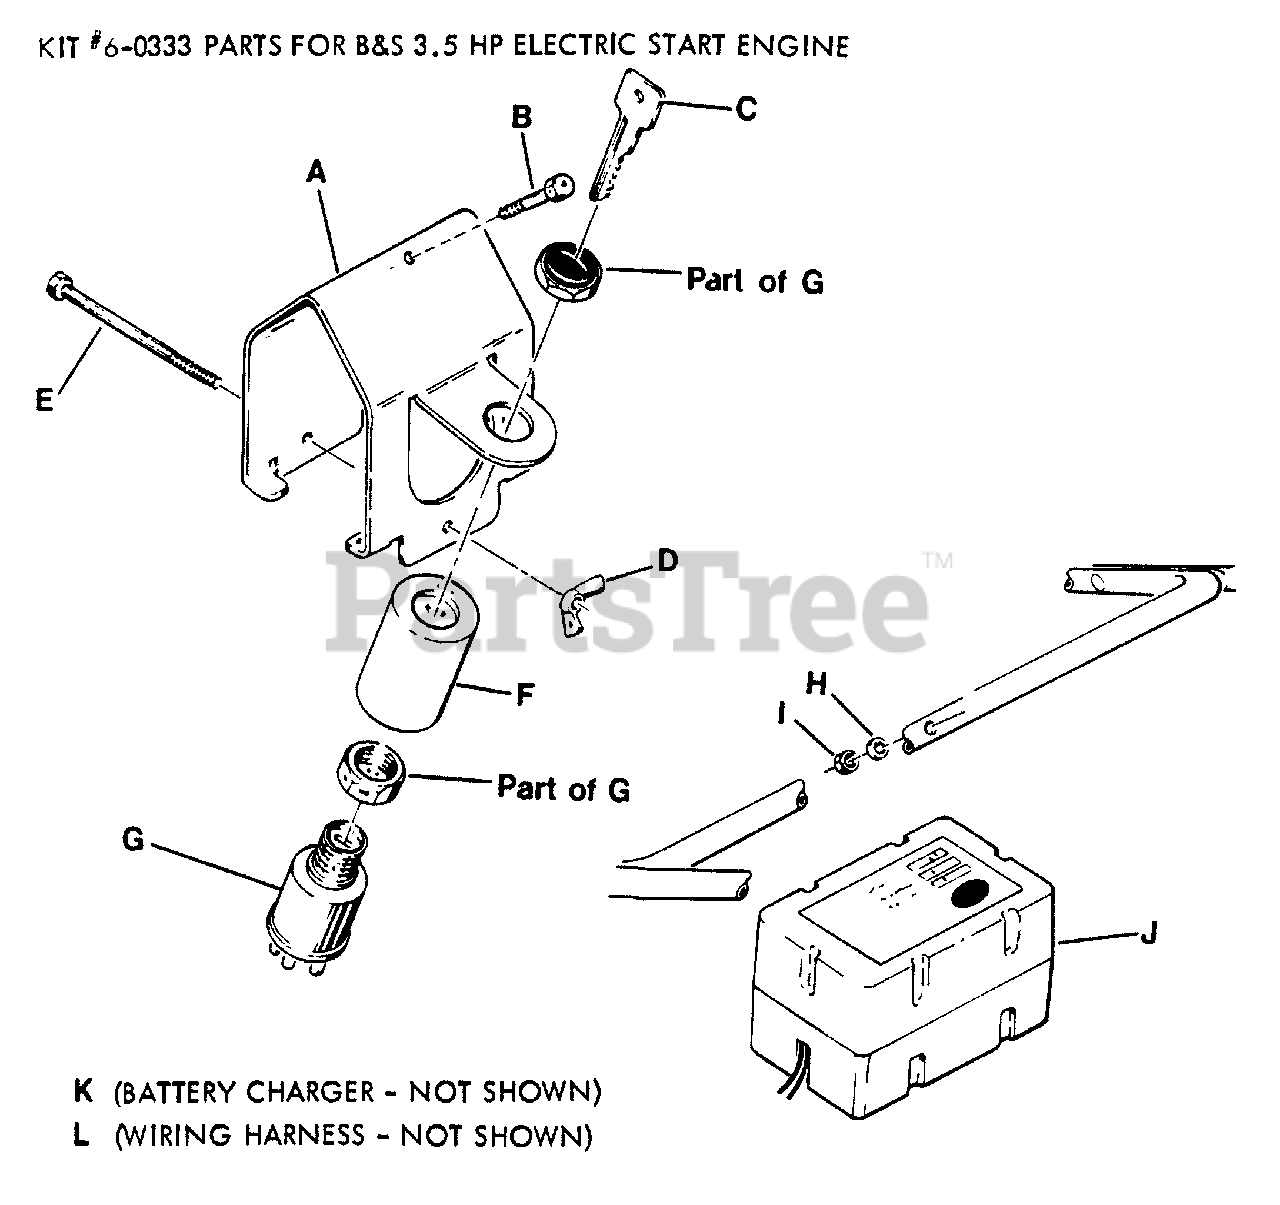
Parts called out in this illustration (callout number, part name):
60333	ELECTRIC START ENGINE
A	ASSEMBLY, Bracket
B	SCREW, 1/4-28 x 1-1/4" Hex Head Cap, Grade 5
C	KEY
D	NUT, 1/4-28 Wing
E	SCREW, 1/4-28 x 3-1/4" Hex Head Cap, Grade 5
F	COVER, Switch
G	SWITCH, Ignition
H	WASHER, 1/4" Internal Tooth Lock
I	NUT, 1/4-28 Hex
J	BATTERY, 12 Volt, 2.5 Amp
